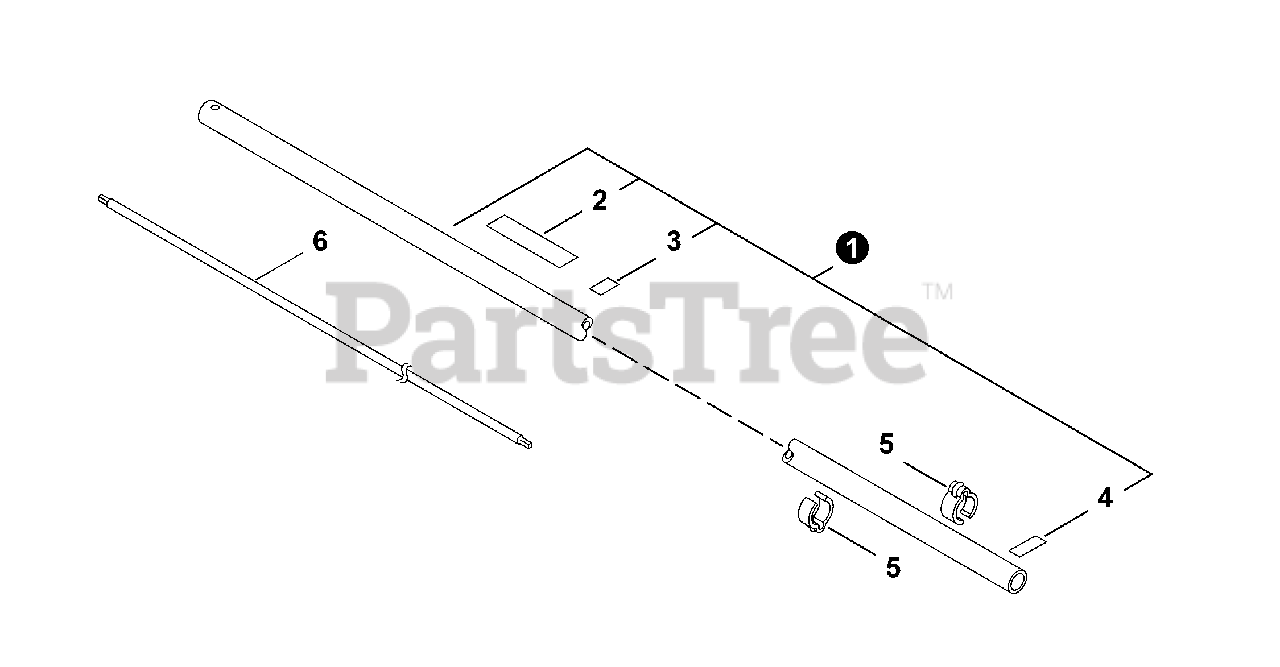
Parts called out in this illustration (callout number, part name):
1	MAIN PIPE ASSY
2	LABEL, CAUTION (BLADE CAPABLE)
3	LABEL, HANDLE
4	LABEL - ALIGNMENT
5	CLIP, CABLE 25MM
6	DRIVESHAFT
